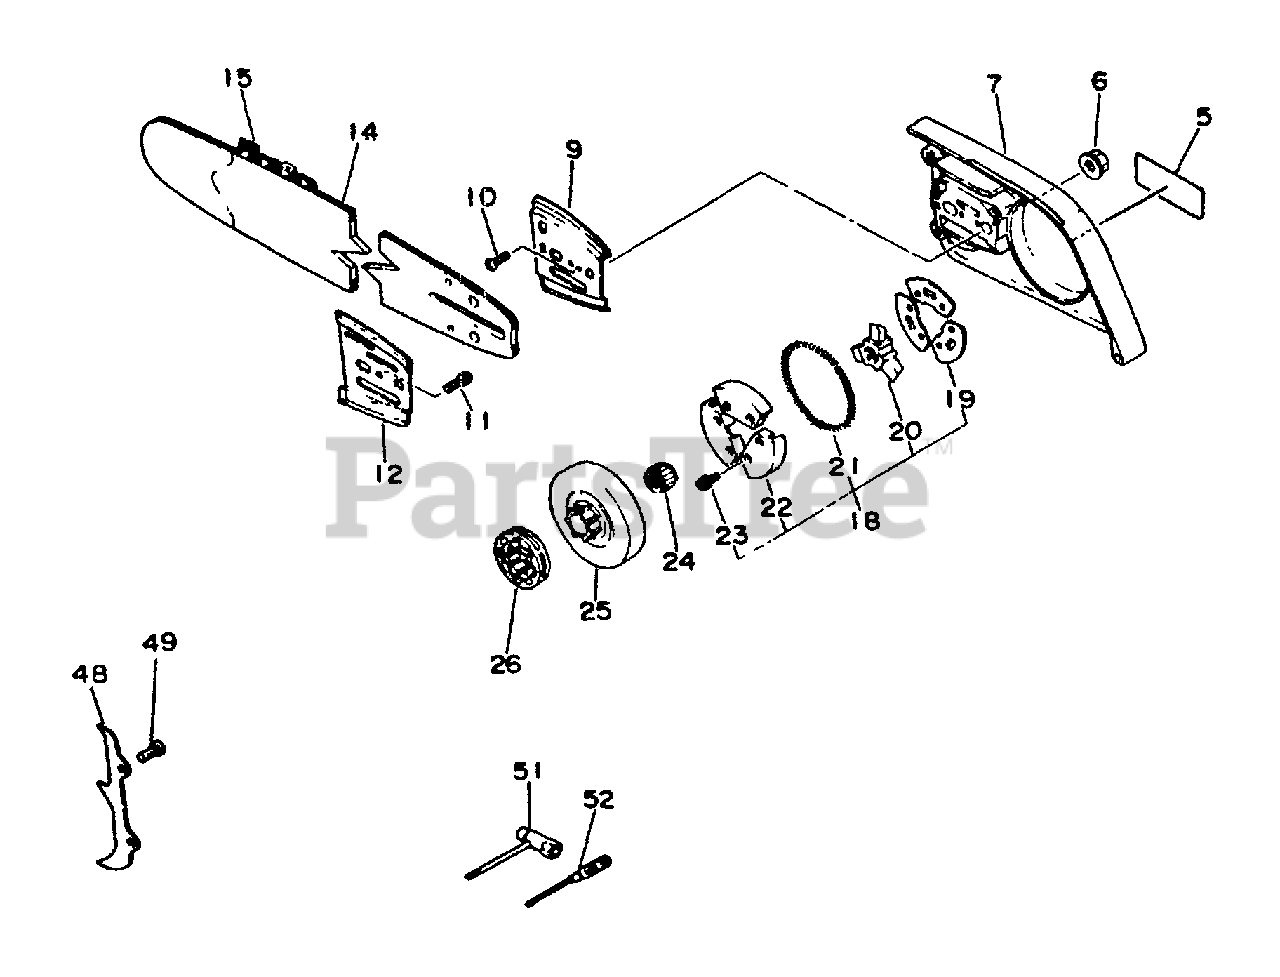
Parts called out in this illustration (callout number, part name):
5	LABEL - ECHO
6	NUT, FLANGE M8×1.25
7	GUARD, SPROCKET
9	PLATE, GUIDE
10	SCREW 3×6
11	SCREW - 4×10
12	PLATE, GUIDE
14	GUIDE BAR
18	CLUTCH ASSY
19	PLATE, CLUTCH
20	HUB, CLUTCH
21	SPRING, CLUTCH
22	SHOE SET, CLUTCH (3PCS)
23	SCREW - 4×8
24	BEARING, NEEDLE
25	DRUM, CLUTCH
26	SPROCKET, 0.325 RIM
48	BUMPER, SPIKED
51	T-WRENCH 13×19×180
52	SCREWDRIVER, PHILLIPS
